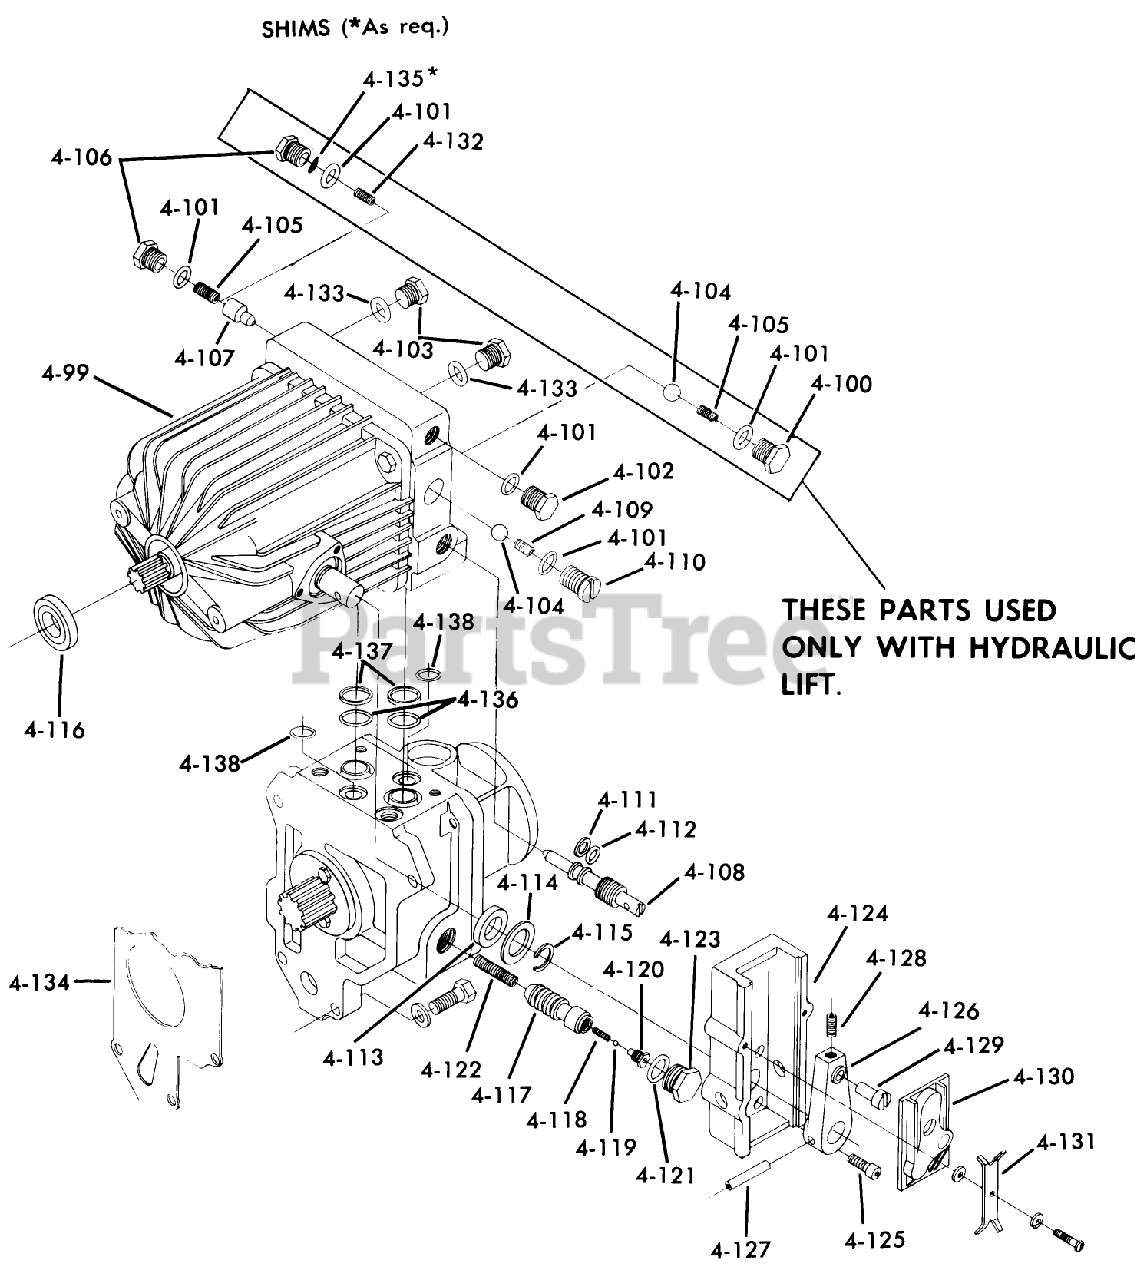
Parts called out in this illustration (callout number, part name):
4-99	SRV.BULLT 437B
4-99	SRV BULLT 437B
4-101	O RING
4-111	O-RING
4-130	CAM
4-134	GASKET
4-136	O RING
4-137	RING BACKUP
4-138	O RING
